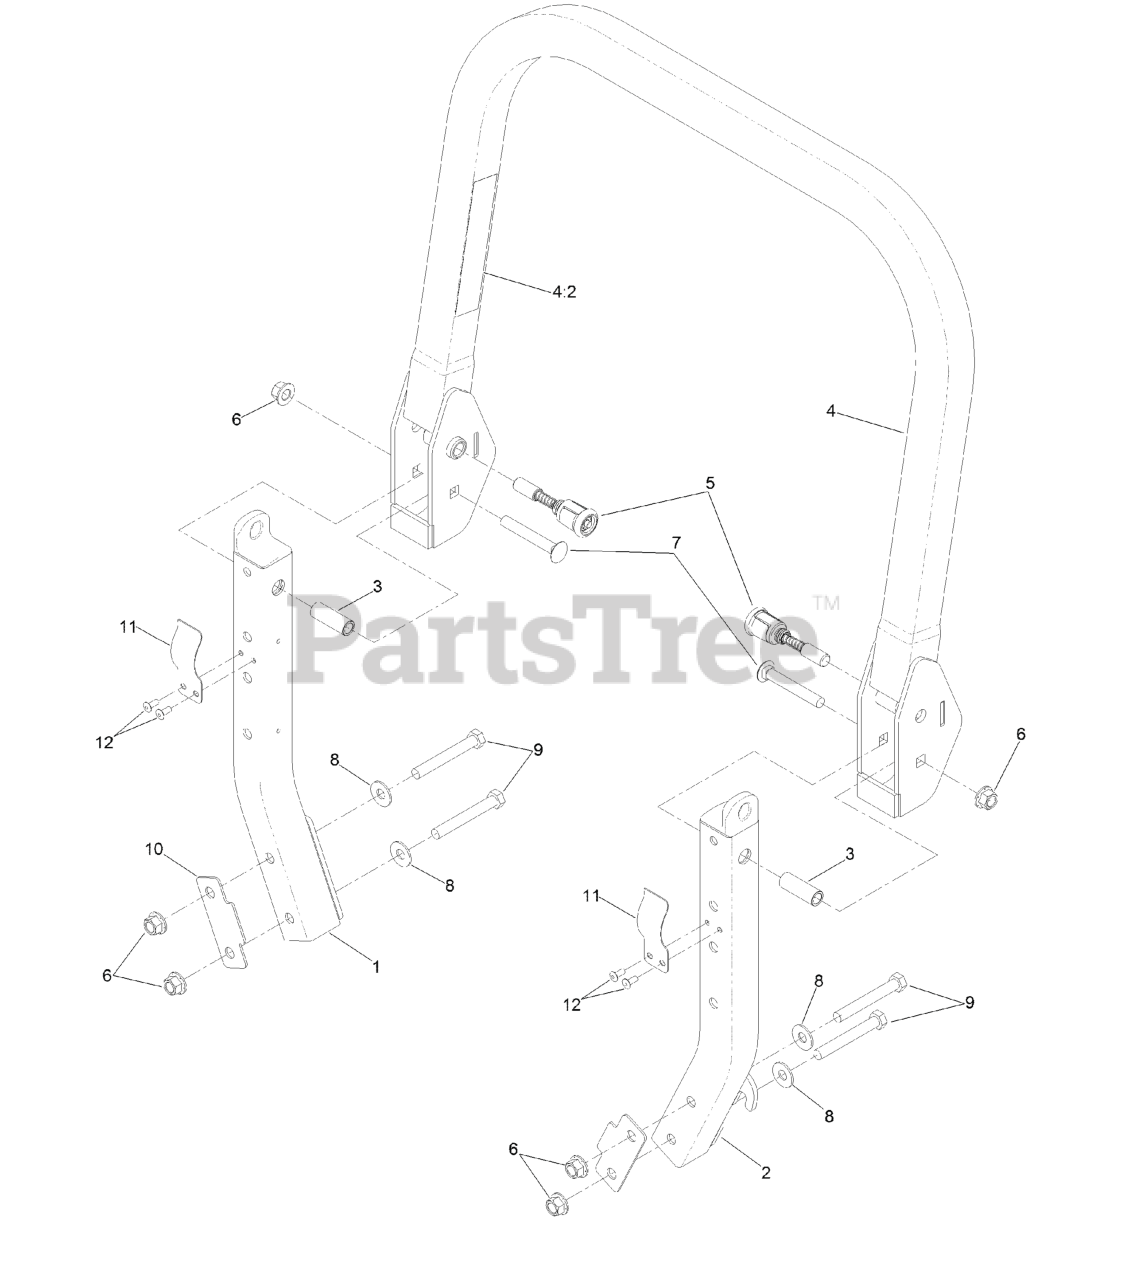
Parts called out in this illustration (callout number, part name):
1	Lower-ROPS, RH
2	Lower-ROPS, LH
4	ROPS UPPER ASM
4:2	DECAL-WARNING
5	PIN-SPRING
6	Nut-Lock 1/2-13
7	SCREW-CARR
8	WASHER-SPRING
9	SCREW-HH
11	SPRING-LEAF
12	RIVET-BLIND
